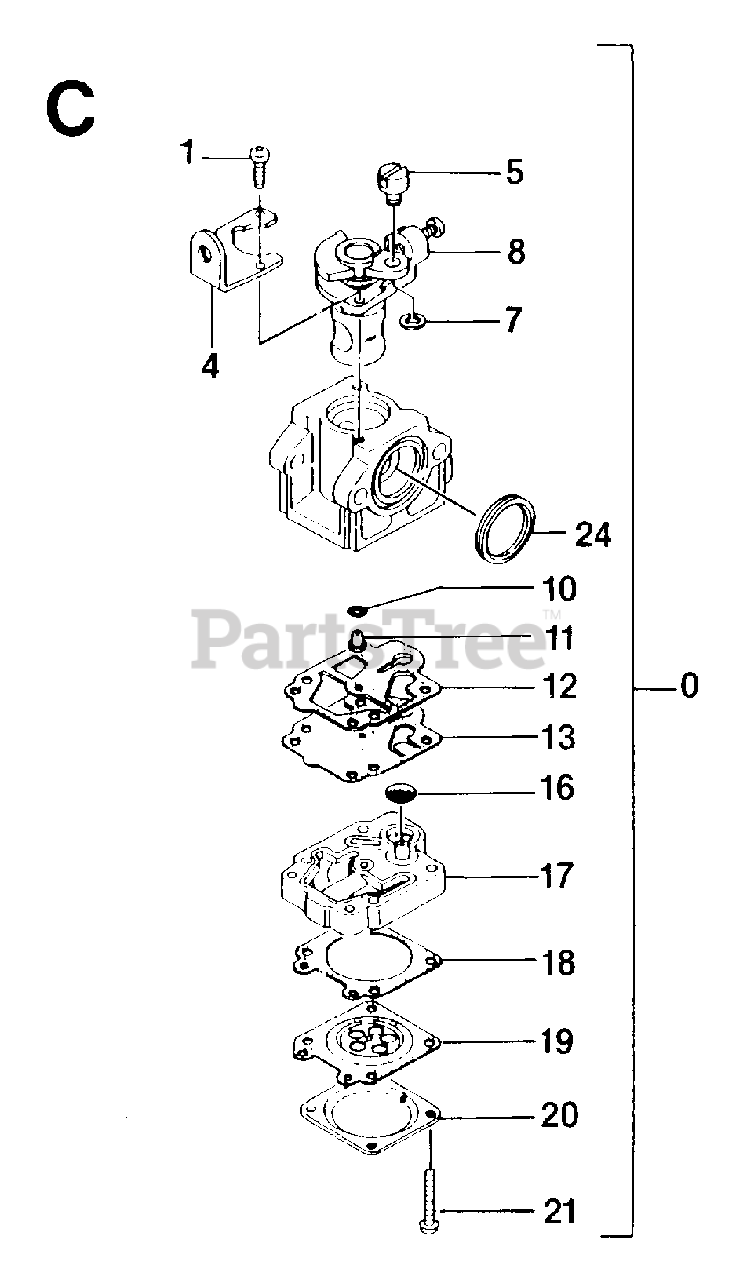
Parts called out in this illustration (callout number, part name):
7	RETAINING RING
19	METERING DIAPHRAGM
20	DIAPHRAGM COVER
24	CLEANER GASKET
